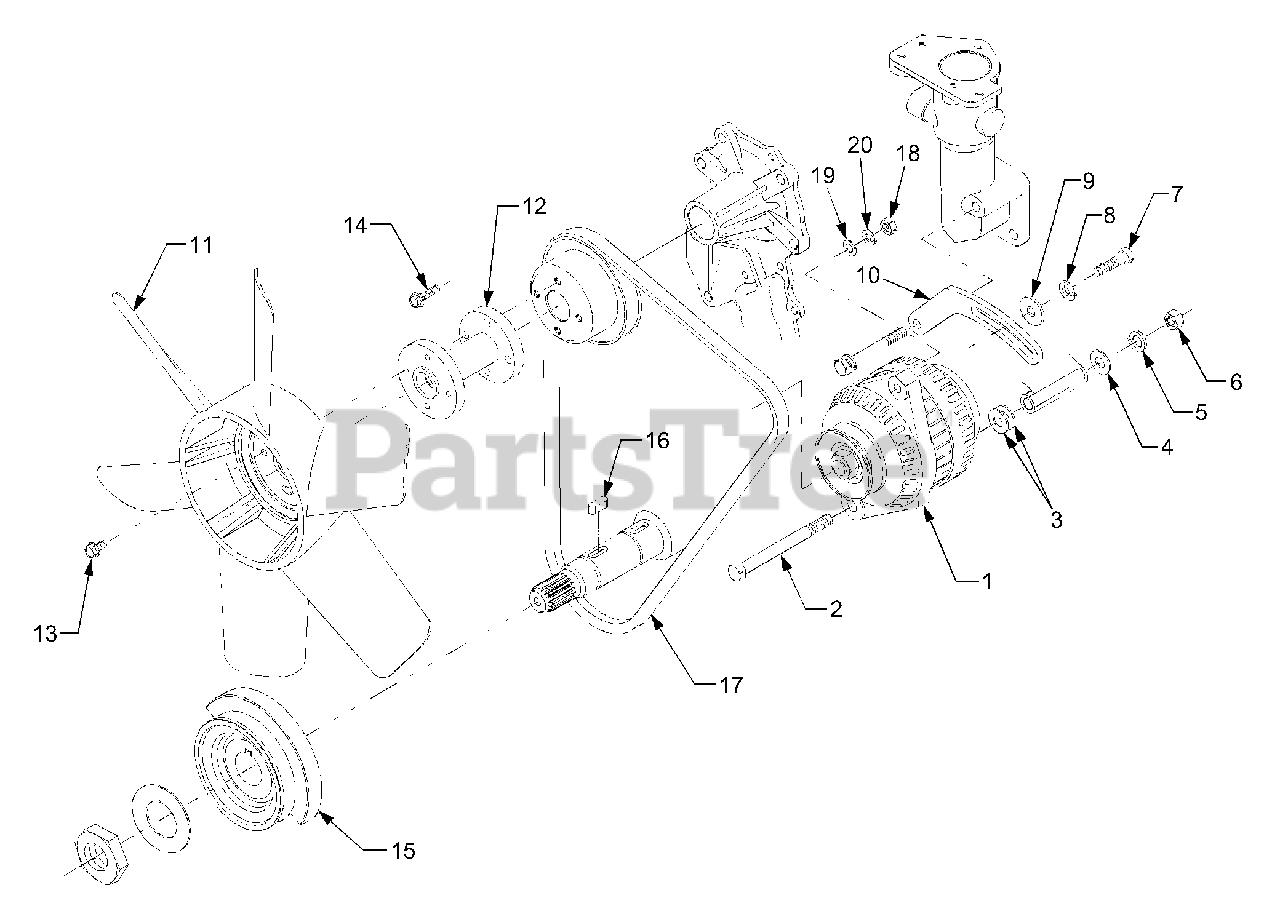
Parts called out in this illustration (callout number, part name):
1	Alternator Ass'y
3	Washer, Plain
4	Washer, Plain
5	Washer, Spring
8	Washer, Spring
9	Washer, Plain
10	Stay, Alternator
11	Fan, Coolling
15	Pulley, Fan Drive
17	Belt, Fan
19	Washer, Plain
20	Washer, Spring
